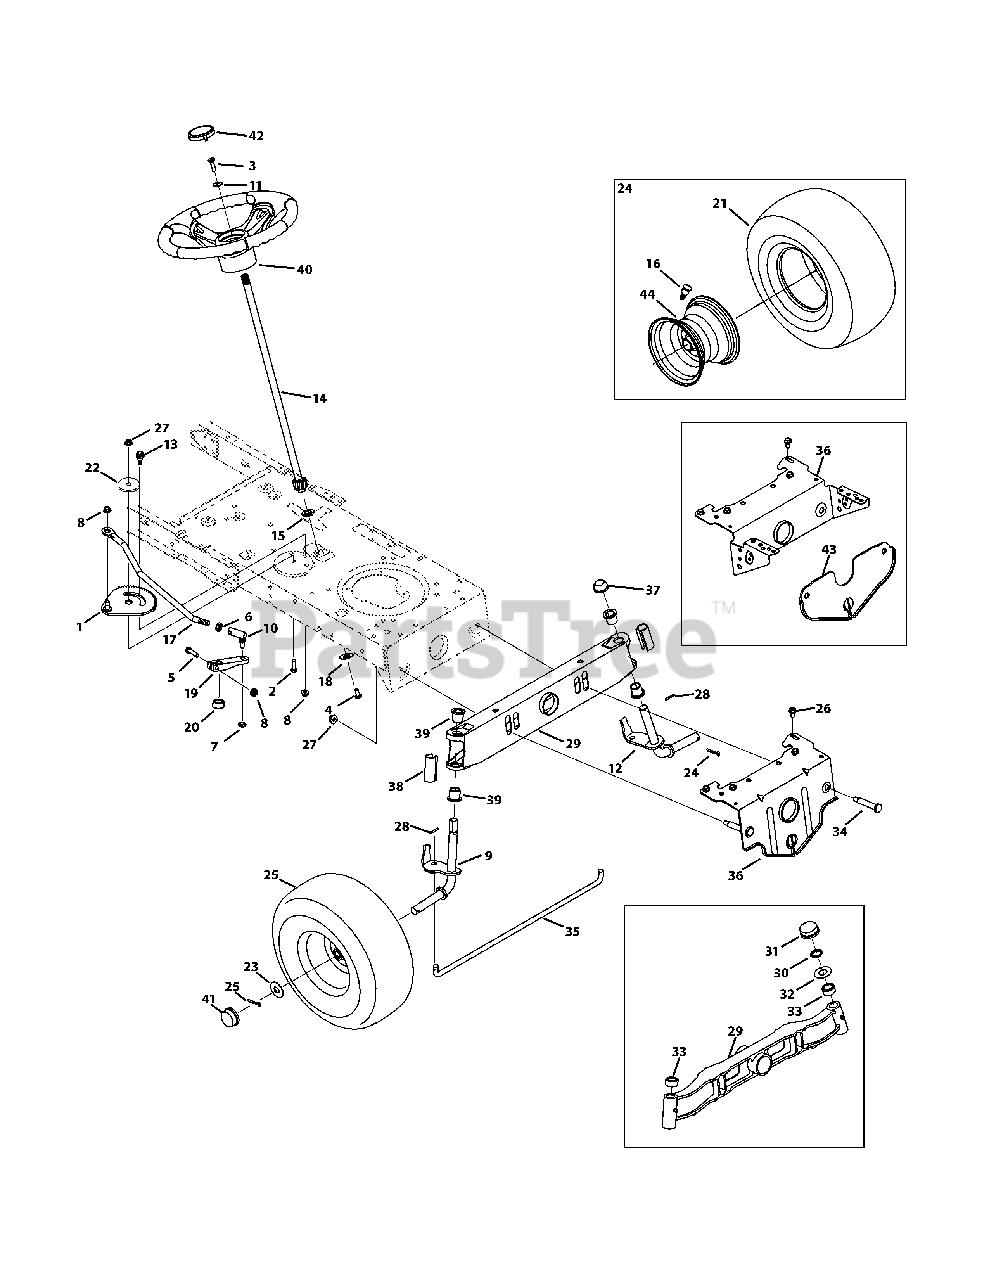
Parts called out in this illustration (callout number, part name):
1	Front Steering Gear Assembly
2	Hex Screw, 3/8-16 x 1.00
3	Hex Screw, 5/16-18 x 1.00, Lock
4	Machine Screw, 5/16-18 x .750
5	Hex Screw, 5/16-18 x 1.75
6	Jam Nut, 7/16-20
7	Jamlock Nut, 3/8-24
8	Flangelock Nut, 5/16-18
9	42" & 46" Front RH Axle
10	Ball Joint, 7/16-20
11	Bell Washer, .340 x .872 x .060
12	42" & 46" Front LH Axle
13	Shoulder Bolt, 5/16-18 x .435 x .350
14	Steering Shaft, 5/8 x 22.08
15	Flange Bearing, 5/8
16	Valve, tubeless Air
17	Steering Link
18	Cap, 1.25 x .16
19	Steering Block
20	Spacer, .71 x .125 x .56
22	Shoulder Spacer, .884 x .190
23	Flat Washer, .781 x 1.590
24	Cotter Pin, 5/32 x 1.25
25	Wheel Assembly, 46"
26	Screw, 5/16-18 x .750
27	Flangelock Nut, 3/8-16
28	Cotter Pin, .125 x .75
29	Pivot Axle
30	Push Nut, 3/4
31	Hub Cap
32	Flat Washer, .78 x 1.59 x .060
33	Spacer, .71 x .125 x .56
34	Shoulder Bolt, 3/8-16 x .500 x 2.38
35	Fixed Rod
36	Pivot Bar Bracket
37	Push Cap, 3/4
38	Standard Axle Cap
39	Flange Bearing, .760 x .941 x 1.0
40	Steering Wheel
41	Hub Cap
42	Sprig Cap
44	Rim Asm, 6.0x4.5, 46" Deck
